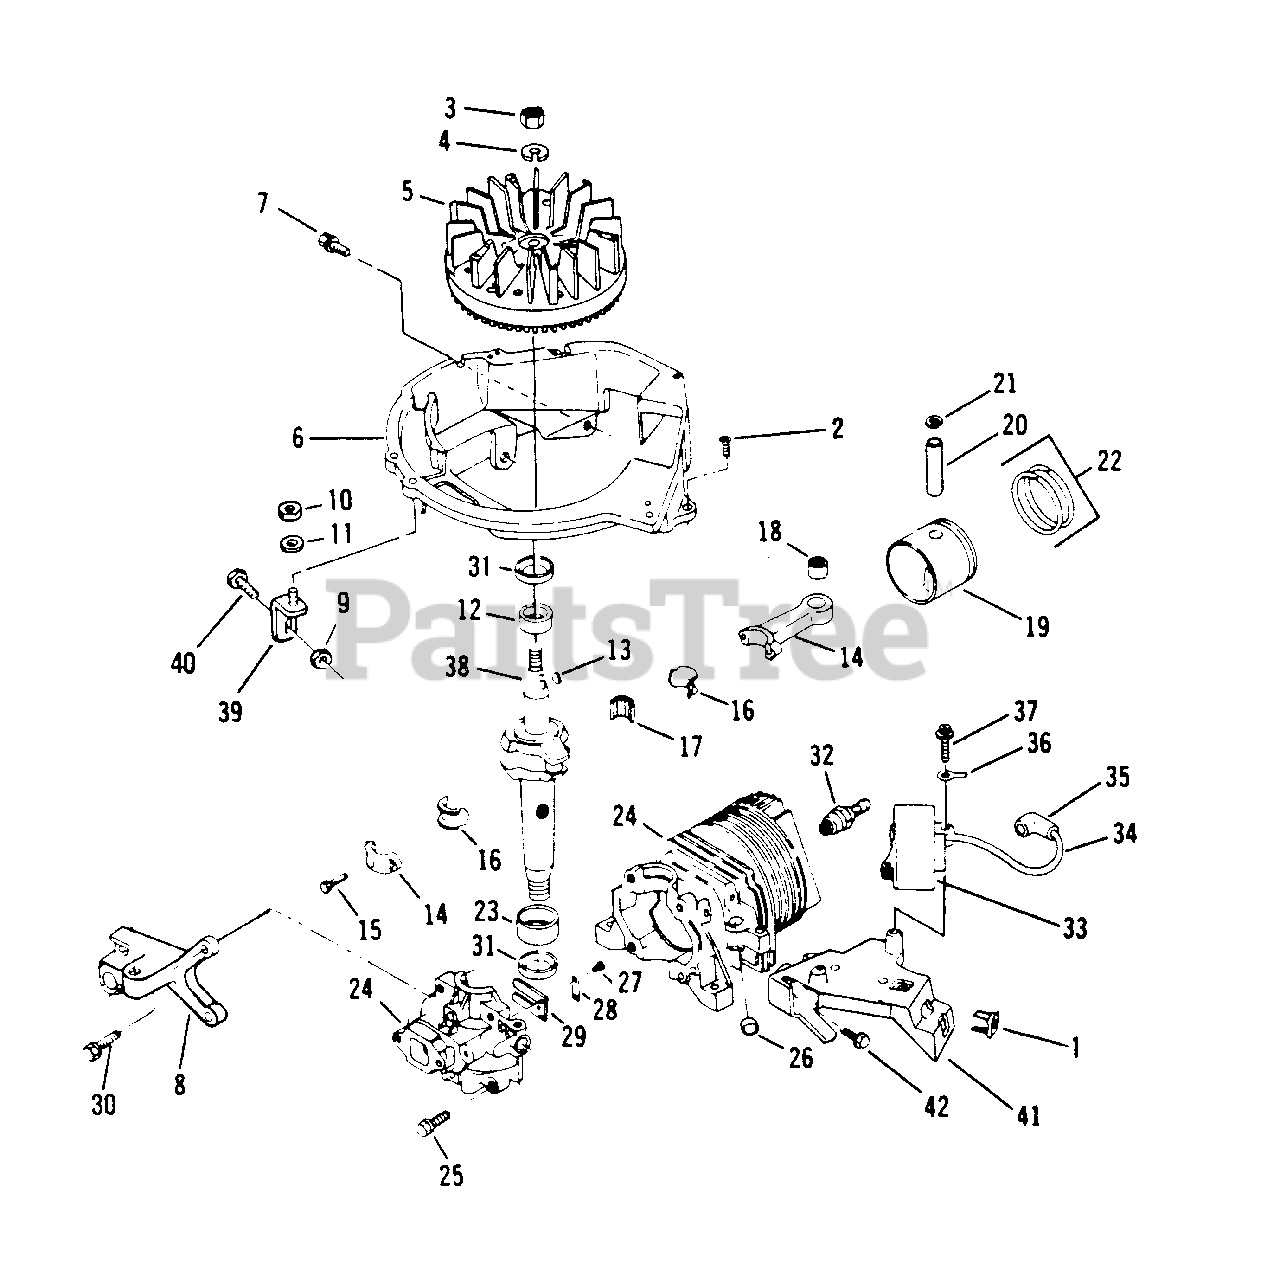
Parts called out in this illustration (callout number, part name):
1	Grommet-C.D. Bracket
2	Screw-Shroud Base to C.D. Brkt.
3	Nut-Flywheel
4	Lockwasher
5	Flywheel Assembly
6	Base-Shroud
7	Screw
8	Bracket-Brake
9	Nut
10	Nut
11	Washer
12	Bearing-Main-Upper
13	Key-Flywheel
14	Connecting Rod Assembly
15	Screw-Cap
16	Liner Split
17	Needle Bearing Set
18	Bearing Assembly
19	Piston and Ring Set
20	Wrist Pin
21	Retaining Ring
22	Ring Set
23	Bearing-Main-Lower
24	Cylinder and Crankcase Cover Assembly
25	Screw-Cover to Crankcase
26	Plug
27	Screw-Reed to Crankcase Cover
28	Plate-Reed Hold Down
29	Reed
30	Screw-Brake Mouting Bracket
31	Oil Seal
32	Spark Plug
33	C.D. Ignition Module and Lead Assembly
34	High Tension Lead and Lower Assembly
35	Spring Terminal
36	Terminal-Ground Lead
37	Screw-C.D. Mounting
38	Crankshaft
39	Brace Assembly
40	Bolt
41	Bracket-C.D. Mouting
42	Screw
